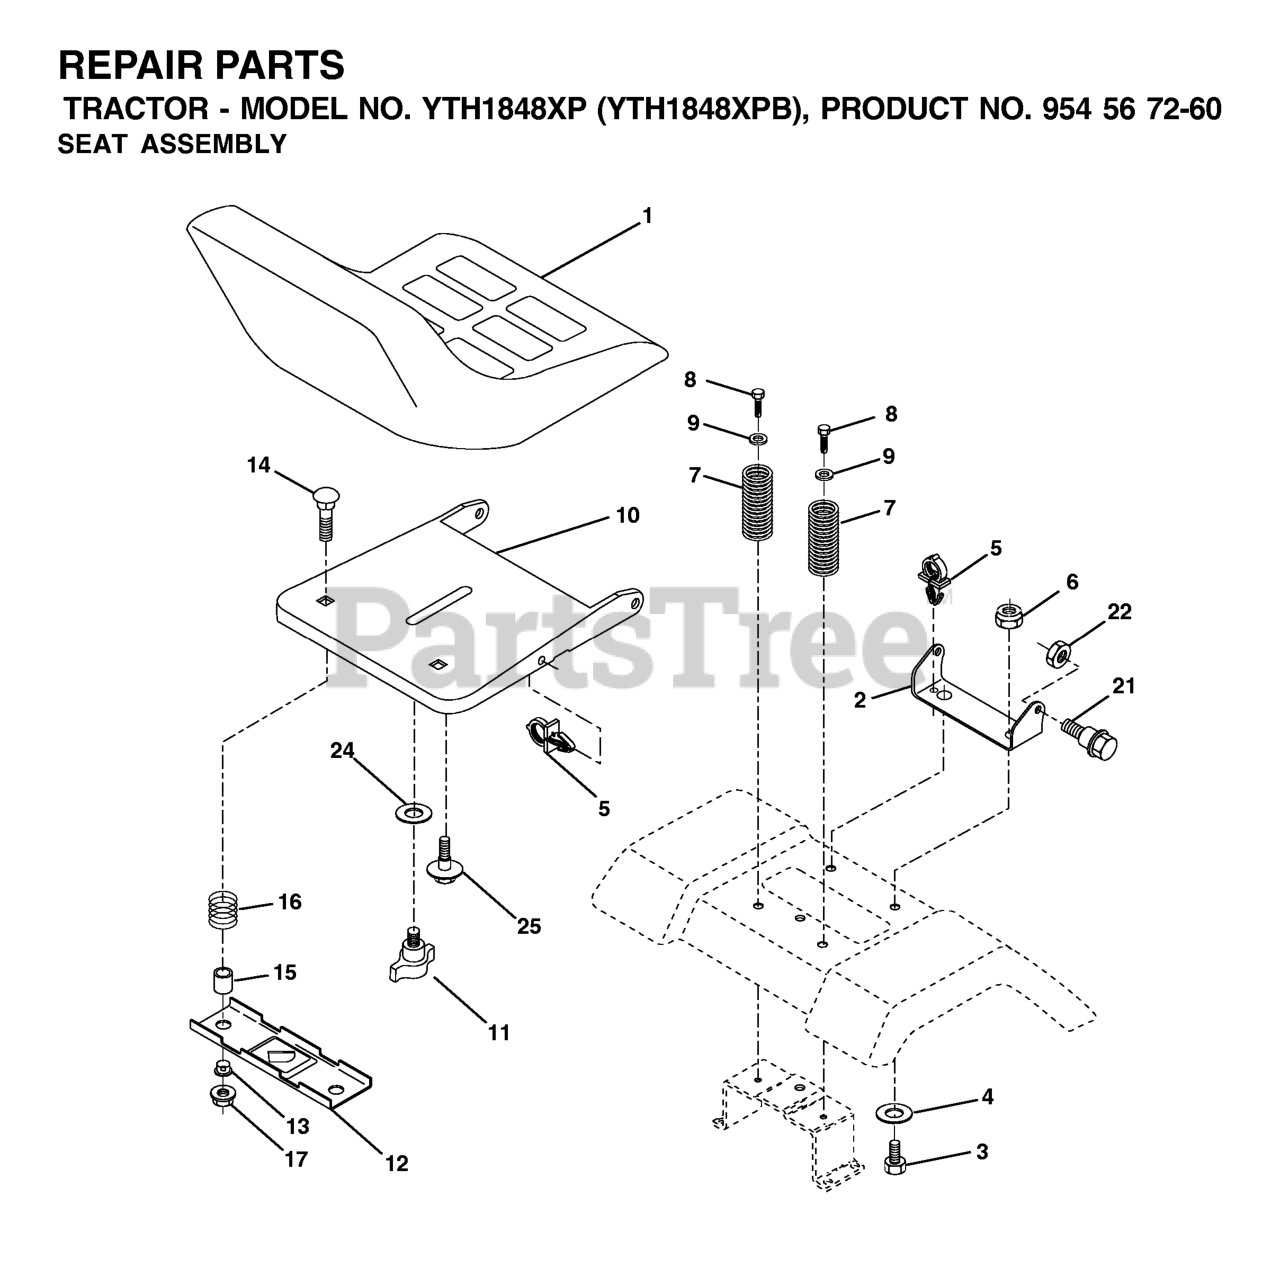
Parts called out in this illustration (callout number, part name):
1	SEAT, GRAY
2	SEAT PIVOT BRKT
3	BOLT, HEX 3/8-16X1
6	NUT
7	SPRING COMPRESSION
8	SCREW 3/8-16X1
9	WASHER
10	PAN, SEAT
11	KNOB.SEAT.ADJ.WINGNUT
12	BRKT SWITCH
14	BOLT.ROUND.HEAD.SQUARE.NECK
15	SPACER SPLIT
16	SPRING COMPRESSED
17	NUT T
21	BOLT.SHOULDER.5/16-18
22	NUT.71038.31-18.HEX.NYLOCK
25	BOLT,SHOULD
